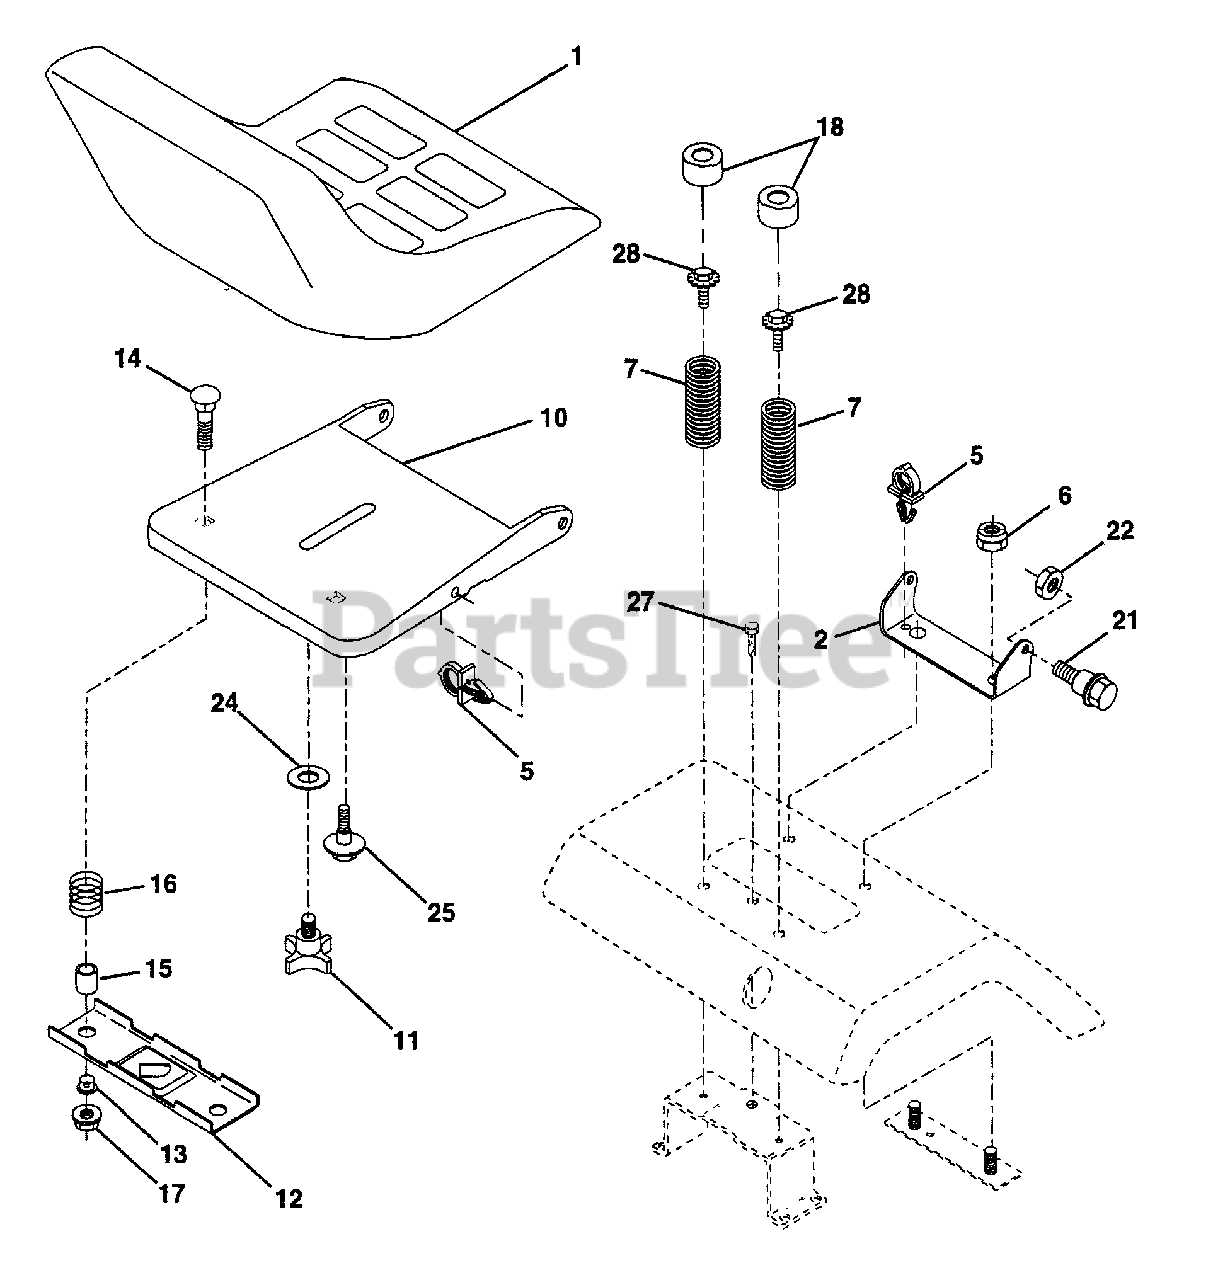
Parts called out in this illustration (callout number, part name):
1	Seat
2	Bracket Pivot Seat 8 720
5	Clip Push-In
6	Nut Lock Hex w/Ins. 3/8-16 UNC
7	Spring Seat Cprsn 2 250 Blk Zi
10	Pan Seat
11	Knob seat 1/2-13 Unc
12	Bracket Mounting Switch
13	Bushing Snap Blk Nyl 50 Id
14	Bolt Rdhd Sht Nk 1/4-20x1-3/8
15	Spacer Split 28x 96 Yel Zinc
16	Spring Cprsn 1 27 Blk Pnt
17	Nut Lock 1/4 Lge Flg Gr 5 Zinc
18	Cap Spring Seat
21	Bolt Shoulder 5/16-18 Unc -2A
22	Nut Hex Lock W/Ins 5/16-18
24	Washer 17/32 X 1-3/16 X 12 Ga.
25	Bolt Shoulder 5/16-18 X 62
27	Screw, Thdrol. 3/8-16 x 12 TY-TT
28	Bolt 5/16-18 UNC x 3/4 w/Sems
